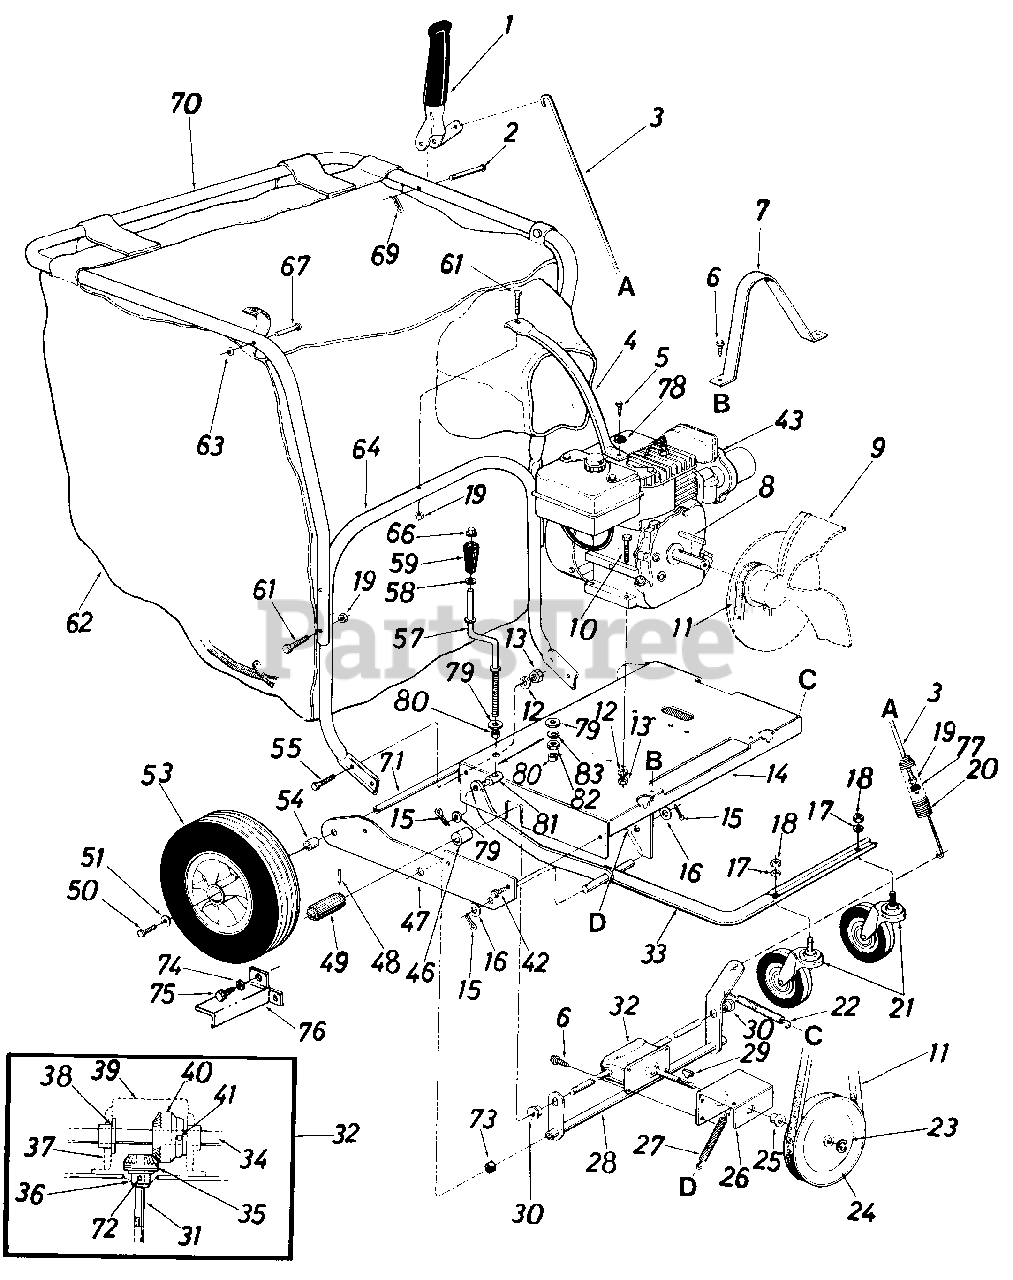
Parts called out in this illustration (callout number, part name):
1	Clutch Grip Ass'y.
2	Clevis Pin .375" Dia. x 1.88"
3	Clutch Rod 32" Lg.
4	Handle Brace
5	Part of Engine
6	Hex L-Wash. Hd. AB Tap Scr. 1/4" x .62" Lg.
9	Air Vane Plate Ass'y.
10	Hex Bolt 5/16-18 x 1.5" Lg. *
11	"V"-Belt 1/2" x 26" Lg.
12	L.Wash. 5/16" I.D.
13	Hex Nut 5/16-18-hd. *
16	Fl.Wash. .63" I.D. x 1.25" O.D.
17	L.Wash. 1/2" I.D.*
18	Hex Nut 1/2-13-hd.*
19	Hex Cent. L.Nut 1/4-20-hd.
20	Extension Spring .38" O.D. x .75" Lg.
21	Swivel Caster Wheel 5" Dia. x 1.25"
22	Extension Spring .38" O.D. x 7.50" Lg.
23	Snap "E"-Ring.50" Dia. Shaft
24	"V"-Pu11ey 5/8 " x 6.50" O.D.
25	Flange Bearing .502" I.D.
28	Clutch Bracket Ass'y.
29	#2 Woodruff Key 3/32" Dia. x .81 " Lg.
30	Hex Flange Bearing Bronze .625" I.D.
31	Pinion Shaft .50" Dia. x 5.0"
32	Gear Box Ass'y. Comp.
33	Caster Arm Ass'y.
34	Drive Shaft .624" Dia. x 22.75" Lg.
35	Bevel Gear .50" I.D. x 14 Teeth
36	Flange Bearing .503" I.D.
37	Gear Box
38	Flange Bearing .630" I.D.
39	Gear Box Cover
40	Bevel Gear .62" I.D. x 28 Teeth
41	Spring Pin Spiral 3/16" Dia. x 1.25" Lg.
42	Hex Wash. Hd. "AB" Tap Scr. 5/16" x .75" Lq.
43	Engine
46	Spacer .63 I.D. x .88" O.D. x .56" Lg.
49	Drive Pinion
50	Hex Locking Bolt 5/16-24 x.62" Lg.
51	Fl.Wash. .34" I.D. x 87" O.D.
53	Wheel Ass'y. - Comp. 12" x 3" (Incl. Ball Bearings)
54	Spacer .63" I.D. x 1.00" O.D. x .94" Lg.
55	Hex Bolt 5/16-18 x .75" Lg.*
57	Height Adjustment Crank
58	Fl.Wash. 138" I.D. x .62" O.D
59	Crank Knob
61	Hex Bolt 1/4-20 x 1.75" Lg.
62	Vacuum Bag- Felt
63	Push Speed Nut .25" Dia. Stud
64	Lower Handle
66	Push Nut 3/8" Dia.
67	Stud Pin .250" Dia. x 1.75"
69	Internal Coter Pin 3/8" Dia.
70	Upper Handle
71	Rear Axle .624" Dia. x 24.37"
72	Spring Roll Pin 5/32" Dia. x 1.12
73	Spacer .82" I.D. x 1.00" O.D. x .305 Lg.
74	L.Wash. .265" I.D.
75	Hex Self Tap Scr. 1/4" x 3/8" Lg.
78	Belleville Washer
79	Fl. Wash. .35" I . D. x .87 " O. D.
80	Spacer .38" I.D. x .50" O.D. x .180" Lg.
81	Ferrule 3/8-8 x .38" Dia.
82	Hex Nut 3/8-8 Thd.
83	L.Wash. 3/8" I.D.*
14530-0498	PLATE-SIDE-RH - OLD CUB YELLOW (0498)
14530-0499	PLATE-SIDE-RH - CUB BEIGE (0499)
14530-0637	PLATE-SIDE-RH - POWDER BLACK (0637)
14530-0638	PLATE-SIDE-RH - MTD/TROY-BILT RED (0638)
